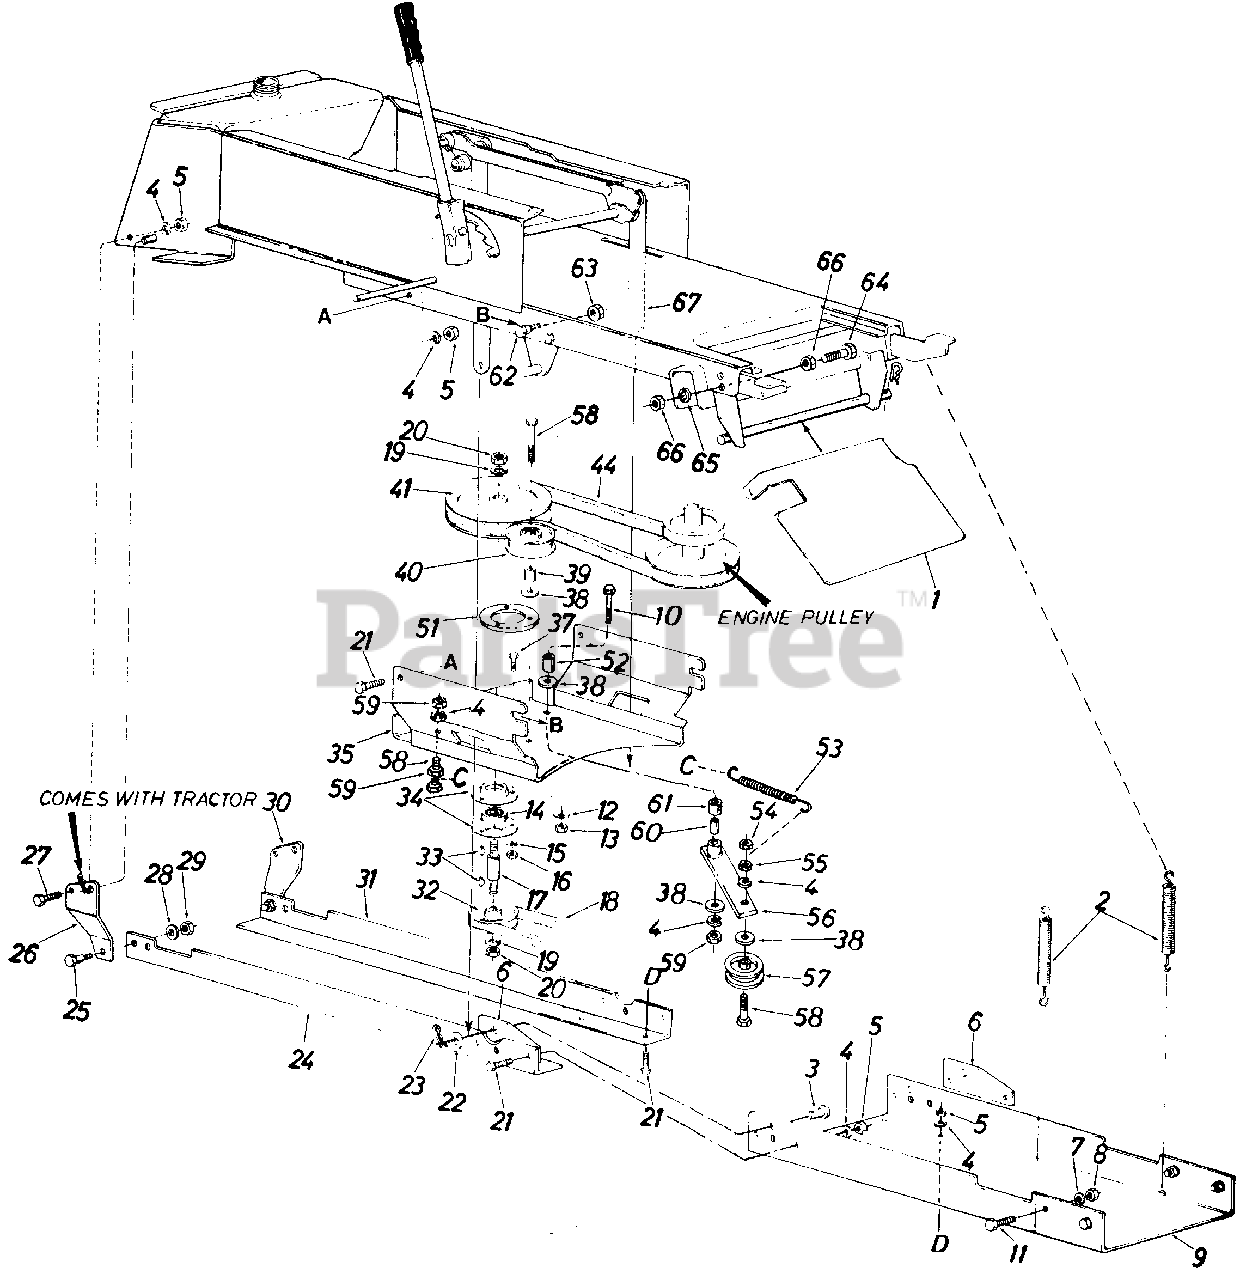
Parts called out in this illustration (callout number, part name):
1	Guide Bracket
2	Helper Spring
3	Clevis Pin
4	L.-Wash. 3/8" I.D.*
5	Hex L.-Nut 3/8-24 Thd.
6	Attaching Plate
7	L.-Wash. 1/2" I.D.*
8	Hex L.-Nut 1/2-20 Thd.
9	Front Support Channel
10	Hex Bolt 3/8-16 x 3.75" Lg.
11	Hex Bolt 1/2-20 x 1.25" Lg.*
12	L-Wash. 3/8" I.D.
13	Hex Jam Nut 3/8-16 Thd.
14	Ball Bearing
15	L.-Wash. 5/16" I.D.*
16	Hex nut 5/16-18 Thd.*
18	"V"Belt
19	L.-Wash. 5/8" I.D.*
20	Hex Jam Nut 5/8-11 Thd.
21	Hex Bolt 3/8-24 x 1.00" Lg.*
23	Internal Cotter Pin
28	Fl.-Wash. 44" I.D. x 1.38" O.D. x .1 30
29	Hex L.-Nut 7/16-24 Thd.
30	Rear Hanger 8rkt.-L.H.
33	#6 Hi-Pro Key 3/16 x 5/8" Dia.
34	Bearing Housing
35	Supporting Bracket
37	Hex Sems Bolt 5/16-18 x 1.00" Lg.
38	Fl.-Wash. .38" I.D. x 1.00" O.D. x .135
39	Spacer .38" I.D. x .62" O.D.
40	Fl.-ldler Pulley
41	Upper Drive Pulley
44	"V" Belt
53	Extension Spring .54" O.D. x 4.75" Lg.
54	Hex Cent. L.-Nut 3/8-16 Thd.
55	Hex Jam Nut 3/8-16 Thd.
56	Idler Arm Ass'y.
57	Idler Pulley
58	Hex Bolt 3/8-16 x 2.25" Lg.
59	Hex Jam Nut 3/8-16 Thd.
60	Spacer.377" I.D. x .60" O.D. x .830" Lg.
61	Spacer .380" I.D. x .630" O.D. x 565" Lg.
62	Shoulder Bolt .498 Dia. x .340
63	Hex Cent. L.-Nut 3/8-16 Thd.
64	Hex Bolt 1/4-28 x 1.50" Lg.
65	L.-Wash. 1/4" I.D.
66	Hex Nut 1/4-28 Thd.
